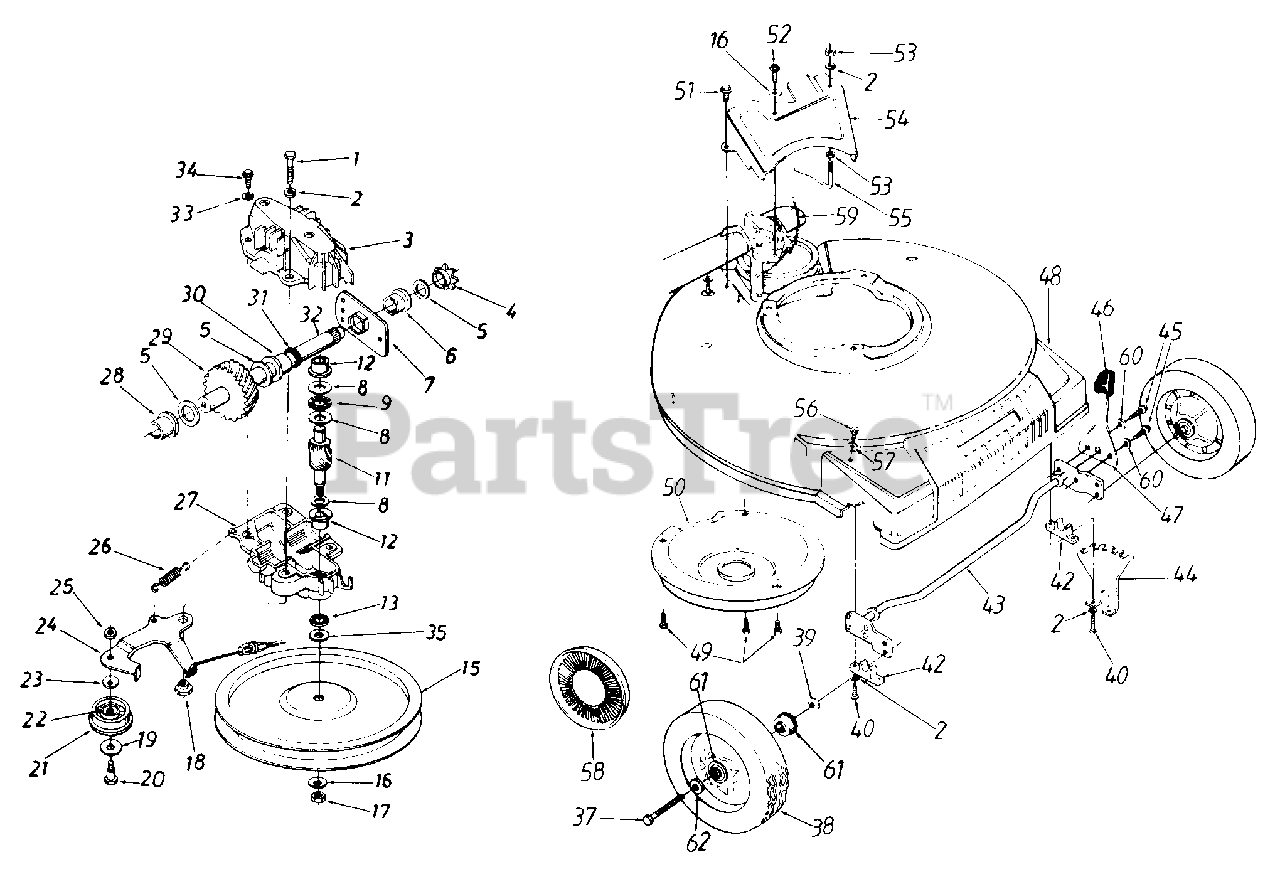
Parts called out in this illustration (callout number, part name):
1	Hex Patch Bolt 1/4-20 x 1.25"
2	L-Wash. 1/4" I.D.
3	Upper Hsg Half
4	#48 Sprocket 7 T x 1/2 Pitch
5	Fl-Wash. 5/8" I.D. x .030
6	Hex Flange Brg. .631" I.D.
8	Thrust Wash. .382" I.D. x .70" O.D.
9	Thrust Bearing .375" I.D. x .812" O.D.
11	11 Tooth Pinion Shaft
12	Flange Bearing
13	Oil Seal
15	Fl-Pulley 5.06" O.D.
16	Bell-Wash. .265" I.D. x .75"
17	Hex L-Nut 1/4-28 L.H. Thd.
18	Shld. Spacer .375" Dia. x .170
19	FI-Wash. .890" I.D. x 1.0"
20	Shld. Bolt .375" Dia. x .40"
21	FI-Idler Plastic 1.50" Dia.
22	Needle Brg. .375" x .31
24	Idler Brk't. Ass'y.
25	Hex Patch L-Nut 1/4-28 Thd.
26	Extension Spring 1.12" Lg.
27	Lower Hsg. Half
28	Flange Bearing .566 Dia.
29	33 Tooth Helical Gear
30	Flange Bearing .629 Dia.
31	Oil Seal .625 Dia.
32	Gear Sprocket Shaft
33	L-Wash. #10 I.D.
34	Hex B-Tap Scr. #10 x .62"
35	Hex Washer .26" x .88"
37	Front Axle Bolt
38	Wheel Ass'y. Comp. 8 x 2"
39	Bell-Wash. .380" I.D. x .88
40	Hex B-Tap Scr. 1/4-20
42	Block Bushing
45	Hex TT-Tap Scr. 1/4-20 x .38"
46	Knob
47	Spring Lever
48	Plastic Front End
49	Hex B-Tap Scr. 1/4" x .38"
52	Hex Wash. Hd. B-Tap Scr. 1/4 x.62"
53	Hex Nut 1/4-20 Thd.
56	Truss B-Tap Scr. 5/16 x .75"
57	Bell-Wash. .345" I.D. x .88"
58	Hub Cap
59	S.P. Cable 44" Lg.
60	External L-Wash. 1/4" I.D.
61	Ball Bearing 1/2" I.D.
62	Wave Wash. .53" I.D. x .78"
